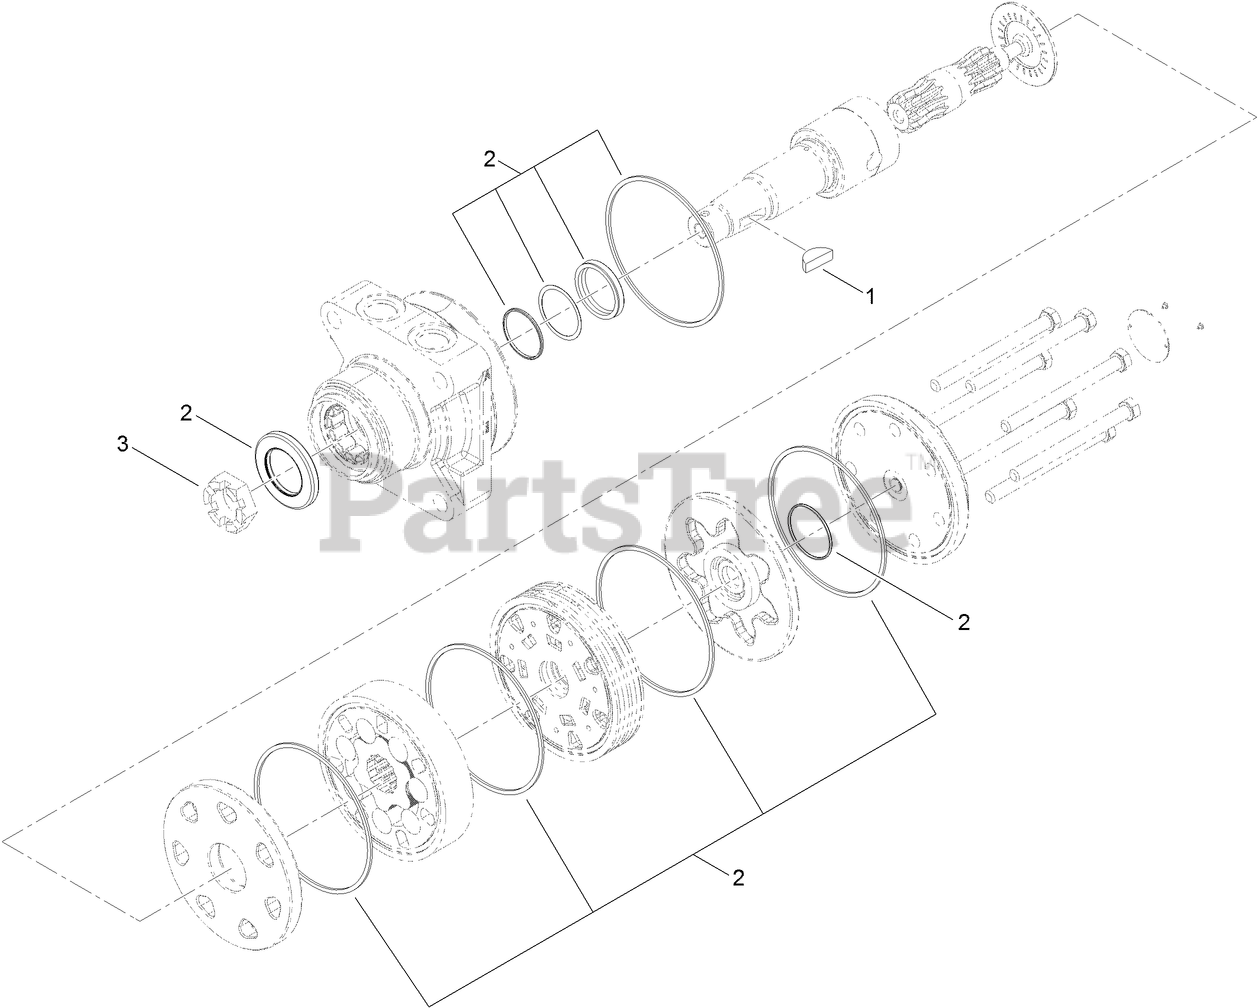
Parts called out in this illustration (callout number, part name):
1	KEY-WOODRUFF
2	SEAL KIT
3	NUT-LOCK
